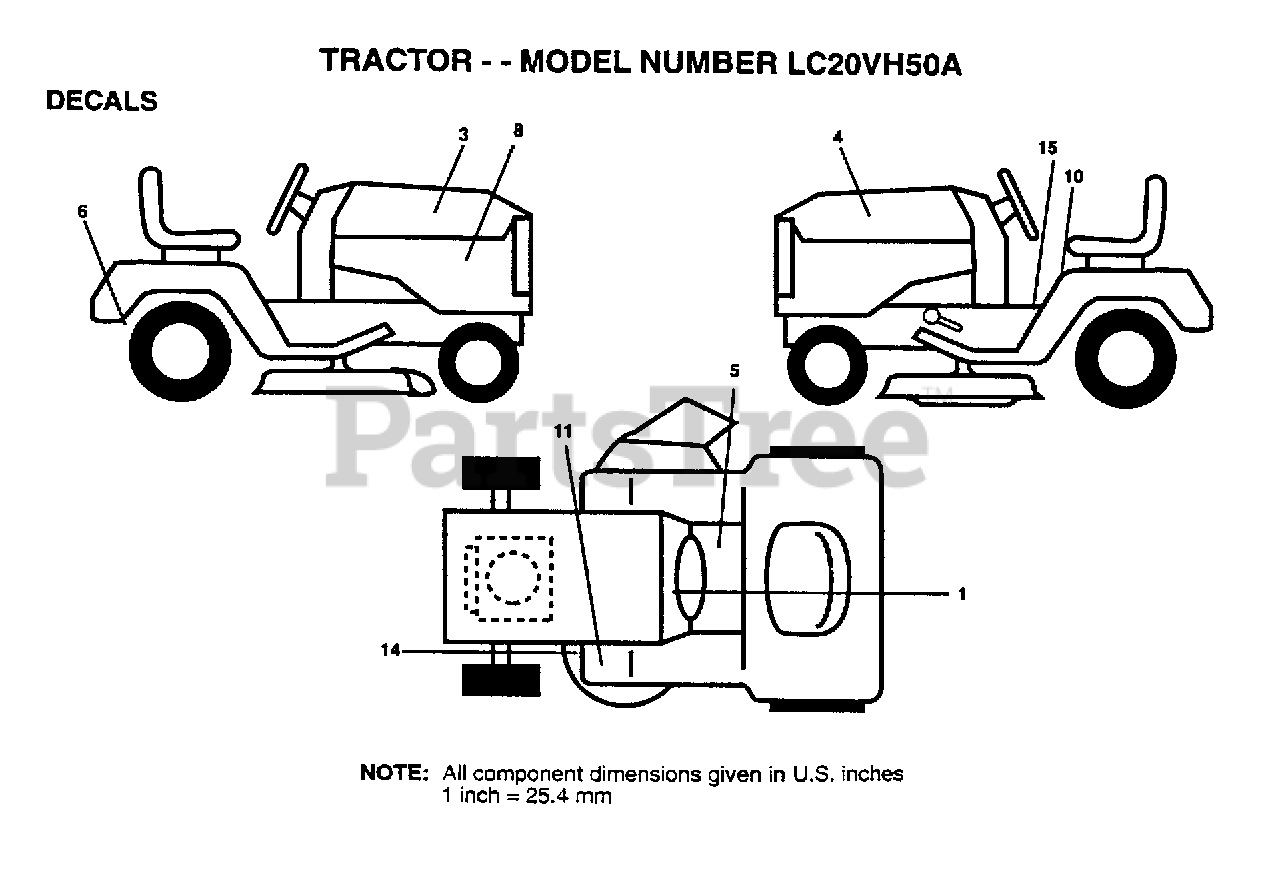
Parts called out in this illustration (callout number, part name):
1	DECAL.DASH.INST.
3	DCL.HD.LC20VH50A
4	DCL.HD.LC20VH50A
5	DECAL BRAK PARK
6	DECAL D-BAR CNTRL
8	DECAL SADLE HYDRO
10	DECAL
14	"DECAL.V.BELT.44"""
